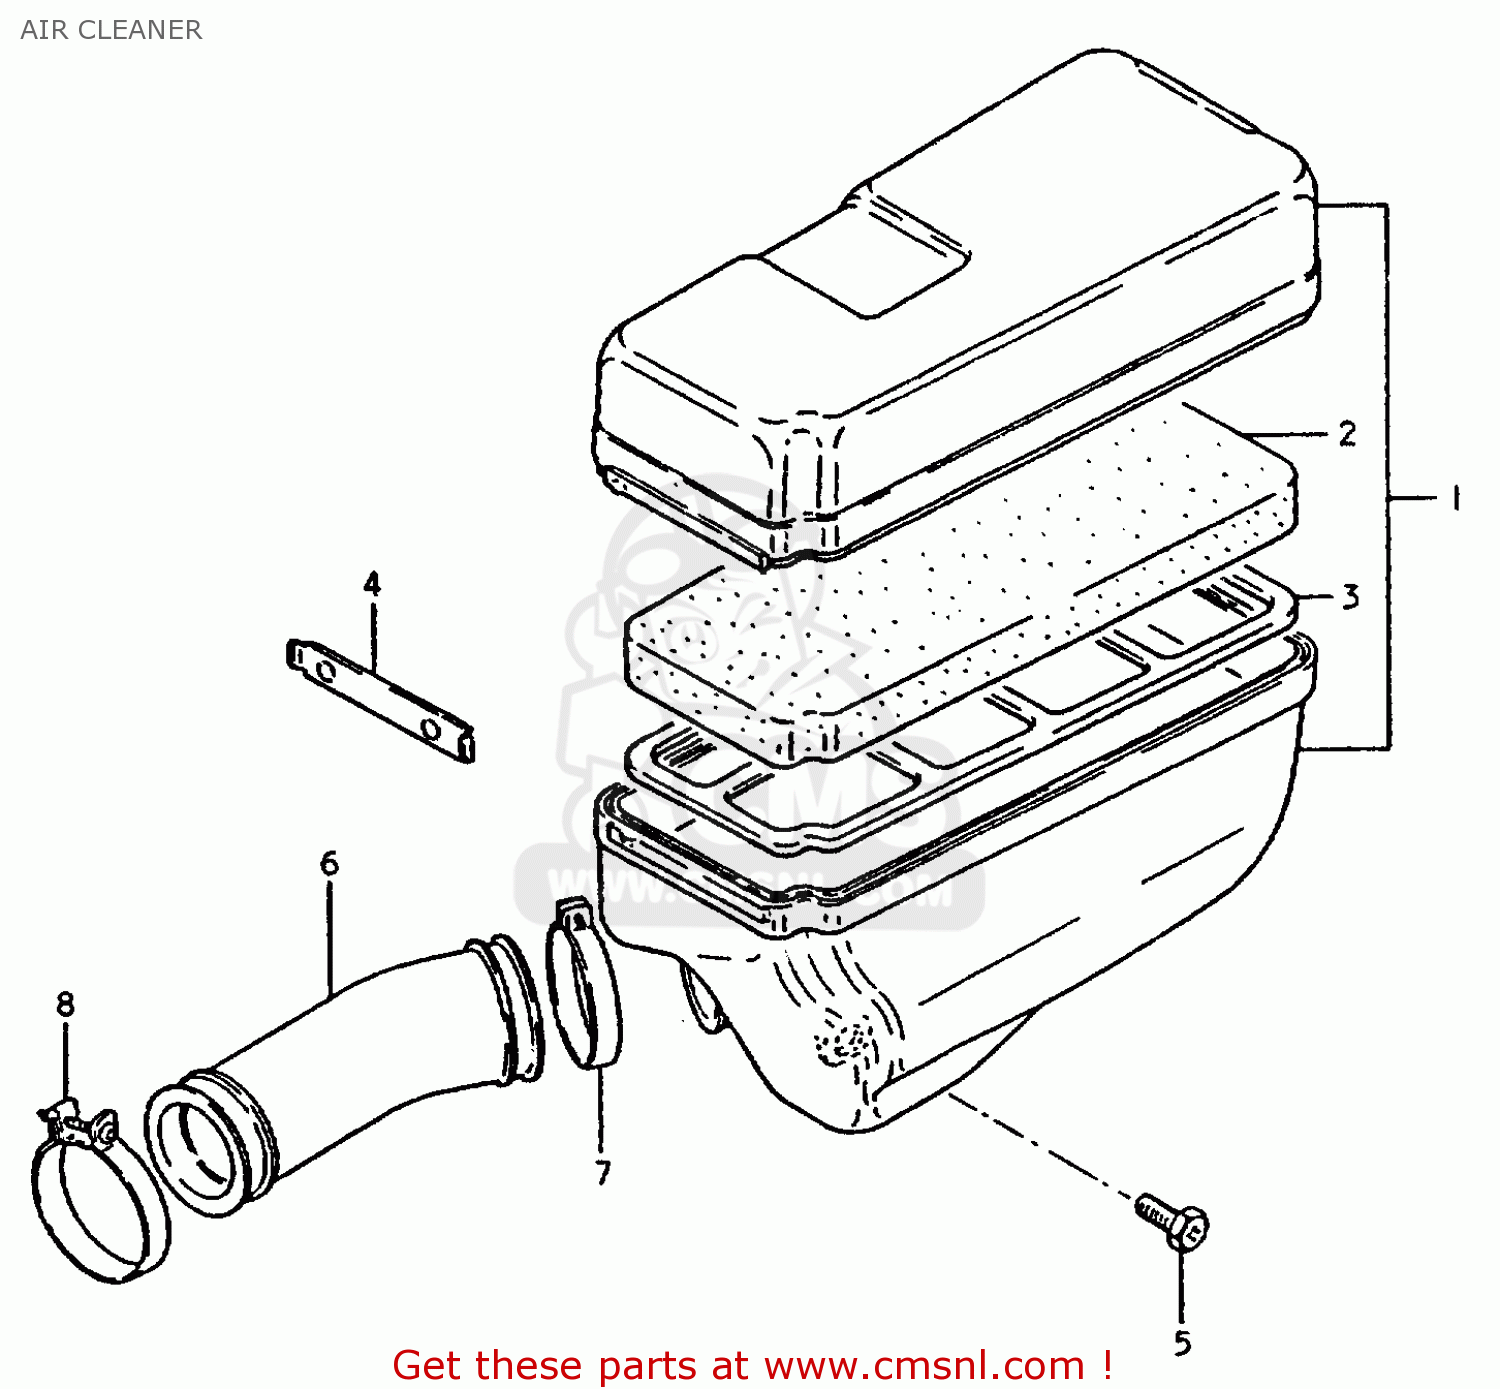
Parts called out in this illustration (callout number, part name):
1	CLEANER ASSY,A
2	FILTER
3	HOLDER
4	SLIDER
5	SCREW
6	TUBE,AIR CLEANER OUTLET
7	CLAMP
8	CLAMP
